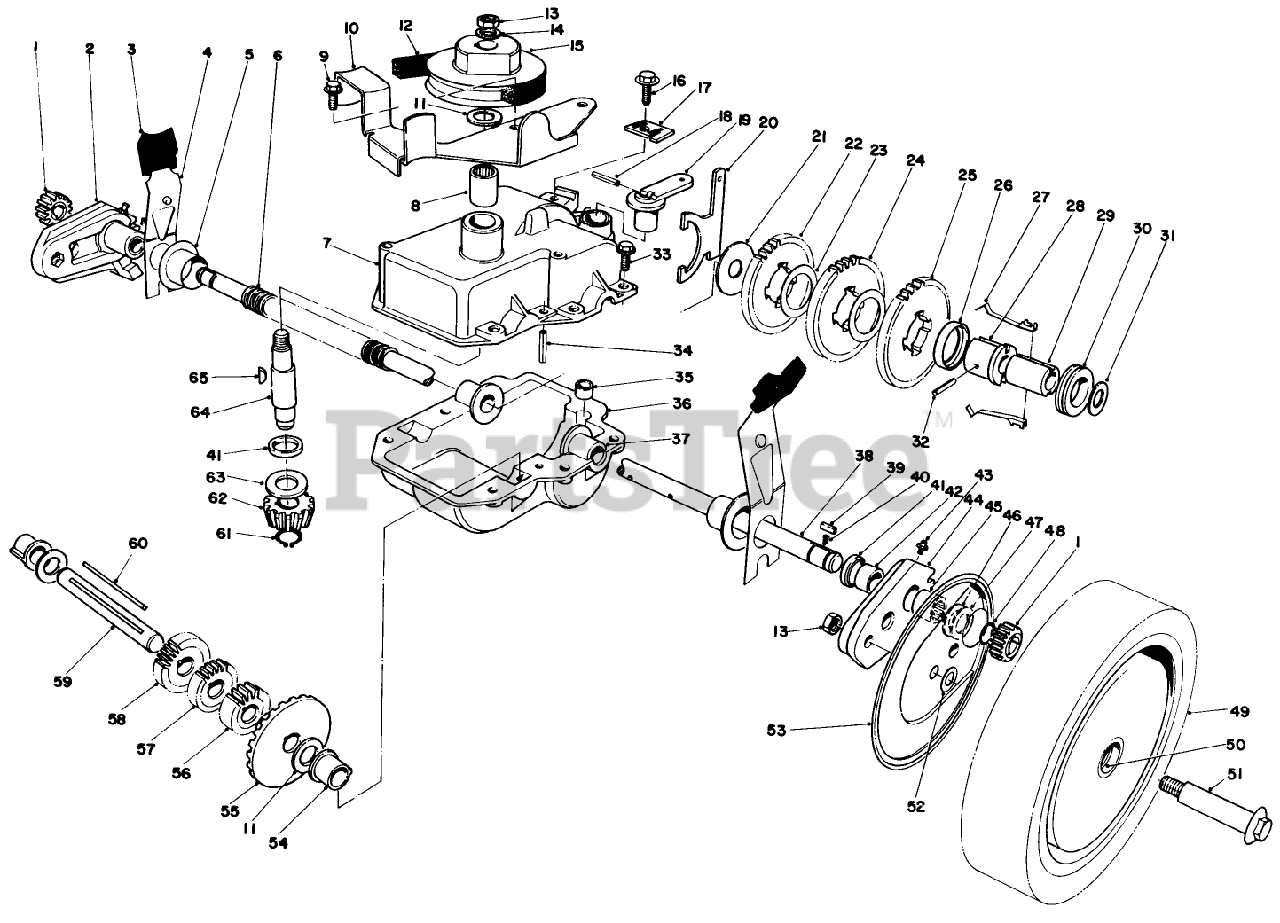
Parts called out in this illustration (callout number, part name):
1	Pinion
3	KNOB-ARM
4	SPRING ARM ASM SP
5	CAP-END
6	CONDUIT-CONVOLUTED, SPLIT
7	DISC PRC4
8	BEARING
9	SCREW
11	WASHER-THRUST
12	V-BELT
14	WASHER-FLAT
15	PULLEY
16	SCREW-THD ROLL, HWH
18	PIN-SPRING
19	LEVER-SHIFT
21	WASHER
22	GEAR-38T
23	WASHER
24	GEAR-42T
29	SLEEVE
30	COLLAR-SHIFT
31	WASHER-PLAIN
33	SCREW-HWH, THREAD ROLL
34	ROLL PIN 3/16 X 1 IN
35	BUSHING-YOKE
39	KEY RECTANGULAR
40	SPRING-COMPRESSION
42	BUSHING
43	FITTING-GREASE
48	RING-RETAINING
50	BUSHING
51	BOLT-WHEEL
52	WASHER
53	WHEEL COVER
54	BUSHING
56	GEAR-12T
57	GEAR-14T
58	GEAR-18T
61	RING-RETAINING
62	PINION-BEVEL
63	WASHER-THRUST
65	KEY-WOODRUFF
